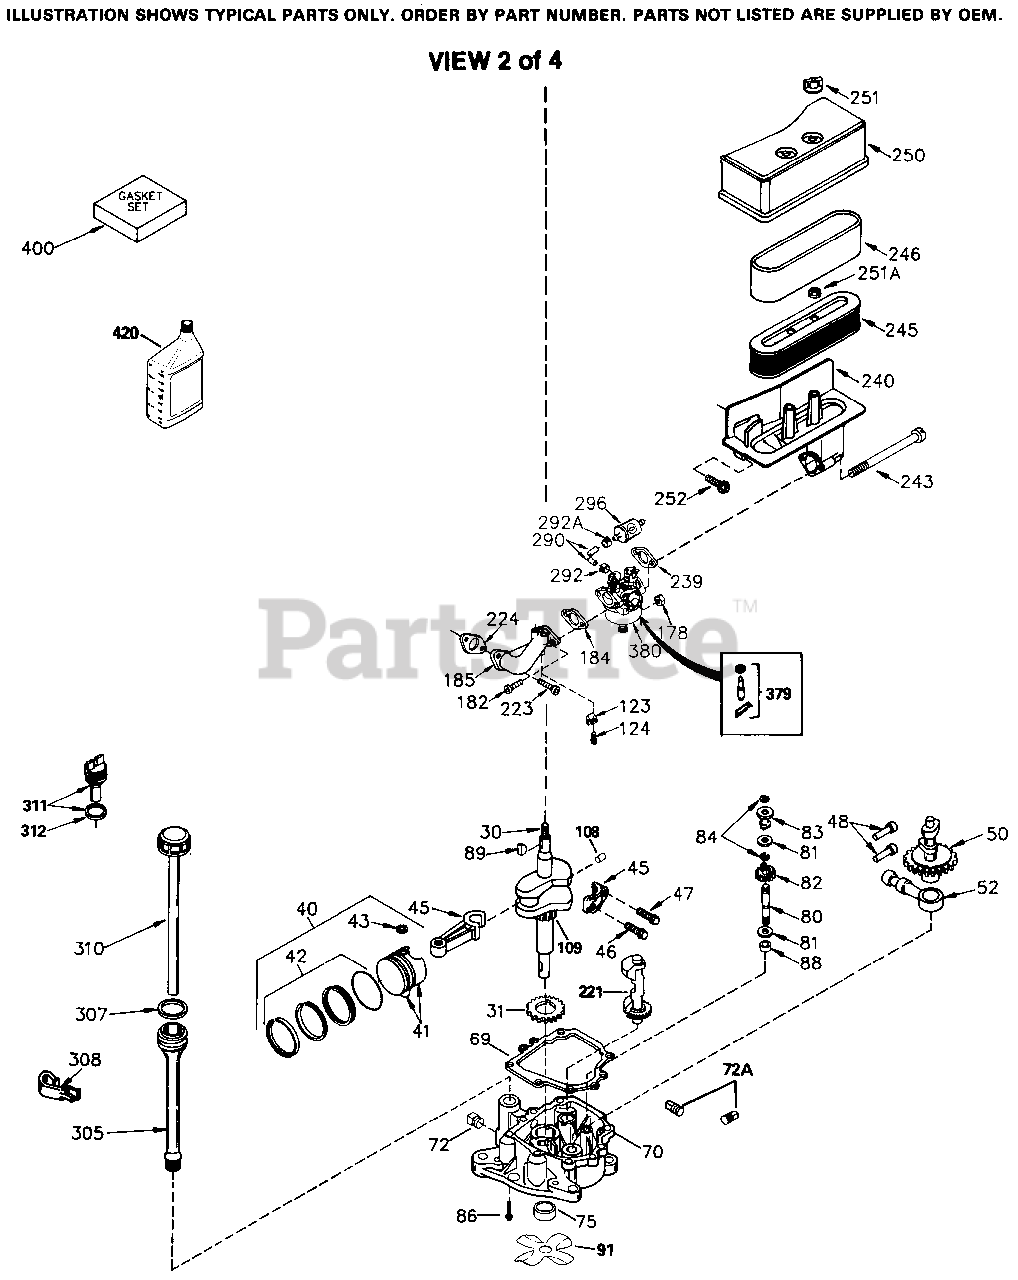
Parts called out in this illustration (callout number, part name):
28	Lock Nut, 8-32
30	Crankshaft
40	Piston, Pin & Ring Set (Std.) ")
40	Piston, Pin & Ring Set (.010" OS)
40	Piston, Pin & Ring Set (.020" OS)
41	Piston & Pin Ass'y. (Std.) (Incl. 43)
41	Piston & Pin Ass'y. (.010" OS) Incl. 43
41	Piston & Pin Ass'y. (.020" OS) Incl. 43
42	Ring Set (Std.) (3-5/16")
42	Ring Set (.010" OS)
42	Ring Set (.020" OS)
43	Piston Pin Retaining Ring
45	Connecting Rod Ass'y. (Incl. 46 & 47)
46	Connecting Rod Bolt
47	Connecting Rod Bolt
48	Valve Lifter
50	Camshaft (MCR)
51	Counterbalance Weight
52	Oil Pump
69	* Mounting Flange Gasket
70	Mounting Flange (Incl. 72, 72A, 75 & 80)
72	Oil Drain Plug
75	Oil Seal
80	Governor Shaft
82	Governor Gear Ass'y. (Incl. 81)
83	Governor Spool
84	Retaining Ring
86	Screw, 1/4-20 x 1-3/16"
88	Spacer (Incl. 81)
89	Flywheel Key
123	Intake pipe Brace
124	Screw, 1/4-20 x 5/8"
178	Nut & Lock Washer 1/4-28
182	Screw, 1/4-28 x 1"
184	* Carburetor To Intake Pipe Gasket
185	Intake Pipe
186A	Choke Link
203	Compression Spring
204	Screw, 6-32 x 1-1/8"
223	Screw, Torx T-30, 5/16-18 x 1-1/8"
224	* Intake Pipe Gasket
238	Screw, 10-32 x 1-17/32"
239	* Carburetor Gasket
240	Air Filter Body (Incl. 239)
245	Air Filter (Incl. 234) also available in Packaged Part #740015B
245A	Pre-Cleaner Air Filter also available in Packaged Part #740015B
250	Air Cleaner Cover
251	Wing Nut, 1/4-20
251A	Nut & Lock Washer, 1/4-20
252	Screw, 1/4-20 x 1"
290	Fuel Line (8.62")
290	Fuel Line (braided 16") (40cm)
305	Oil Fill Tube
307	"O" Ring
308	Fill Tube Clip
310	Dipstick
315	Alt. Coil (3/5 Split) Incl. 321, 322 & 323
379	Inlet Needle, Seat & Clip Ass'y.
380	Carburetor (Incl. 184) (Refer to Divi sion 5, Section A, page A4-6 for brea kdown or Fiche 10B, Grid E-9)
400	* Gasket Set (Incl. items marked *)
420	SAE 30 4-Cycle Engine Oil (Quart)
